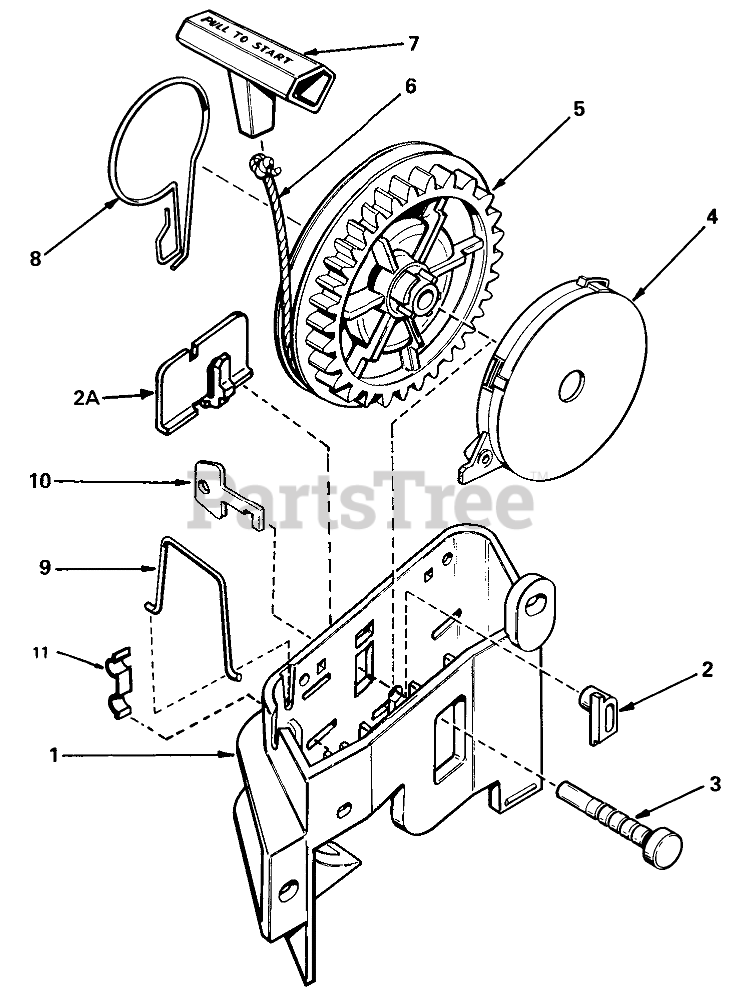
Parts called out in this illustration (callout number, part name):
1	Bracket Starter
2	Pawl, Locking Not used on all engine models)
2A	Clip, Starter Bracket (Used On Starters Not Equipped With Pawl, Ref. No. 2)
3	Pin-Pulley
4	Spring Assy., Rewind (Incl. Ref. #3)
6	Rope Starter (Length 65" & 9/64" Dia.)
7	Handle-Starter
9	Clip-Rope
10	Key (Not Used On All Engine Models
11	Washer-Thrust
